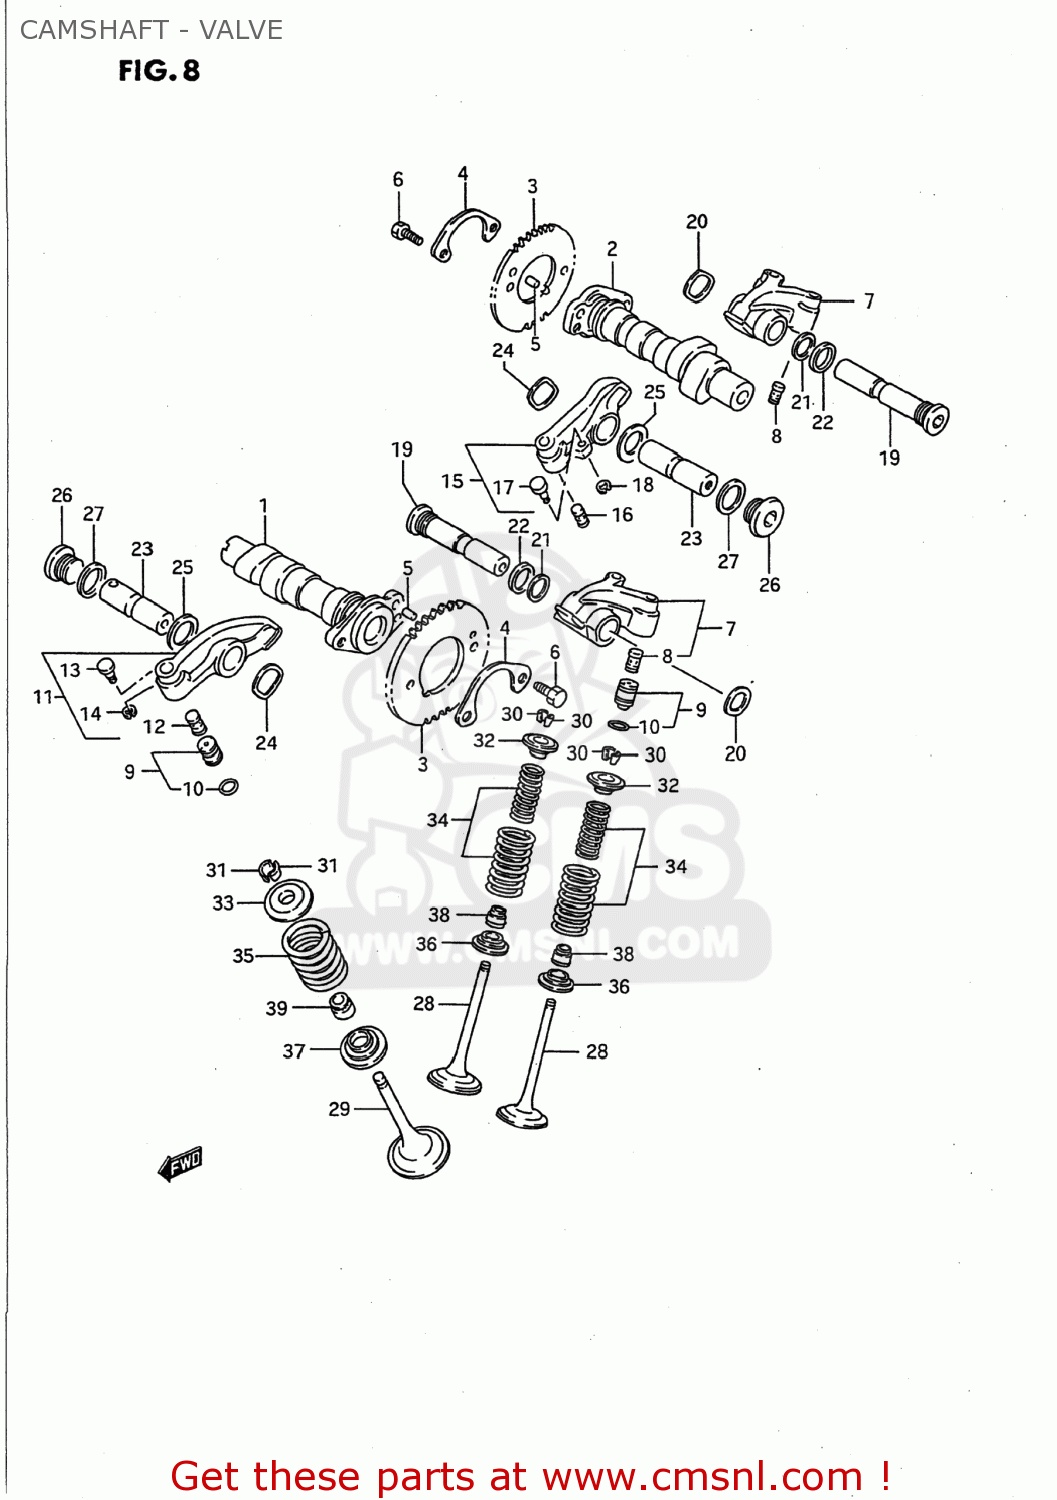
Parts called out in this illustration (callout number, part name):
1	CAMSHAFT,FR
2	CAMSHAFT,RR
3	SPROCKET,CAMSHAFT
4	WASHER,CAM CHAIN SPROCKET
5	PIN
6	BOLT(6X12.5)
7	ARM,VALVE ROCKER INTAKE
8	CHAMBER,VALVE LASH ADJUSTER
9	ADJUSTER,HYDRAULIC VALVE
10	O-RING,ADJUSTER
11	ARM,VALVE ROCKER FR EXHAUST
12	CHAMBER,VALVE LASH ADJUSTER
13	PIN,DECOMP
14	E RING
15	ARM,VALVE ROCKER RR EXHAUST
16	CHAMBER,VALVE LASH ADJUSTER
17	PIN,DECOMP
18	E RING
19	SHAFT,INTAKE VALVE ROCKER ARM
20	WASHER
21	WASHER
22	GASKET(16X22X2) (NAS)
23	SHAFT,EXHAUST VALVE ROCKER ARM
24	WASHER
25	WASHER(16X26X1)
26	PLUG,18X11
27	GASKET(18X24.2X2) (NAS)
28	VALVE,INTAKE
29	VALVE,EXHAUST
30	COTTER,VALVE
31	COTTER,VALVE
32	RETAINER,VALVE SPRING
33	RETAINER,VALVE SPRING
34	SPRING SET,VALVE
35	SPRING,VALVE OUTER
36	SEAT,VALVE SPRING
37	SEAT,VALVE SPRING
38	SEAL,OIL(5.5X11X8.2)
39	SEAL,OIL(7X14.4X9)
